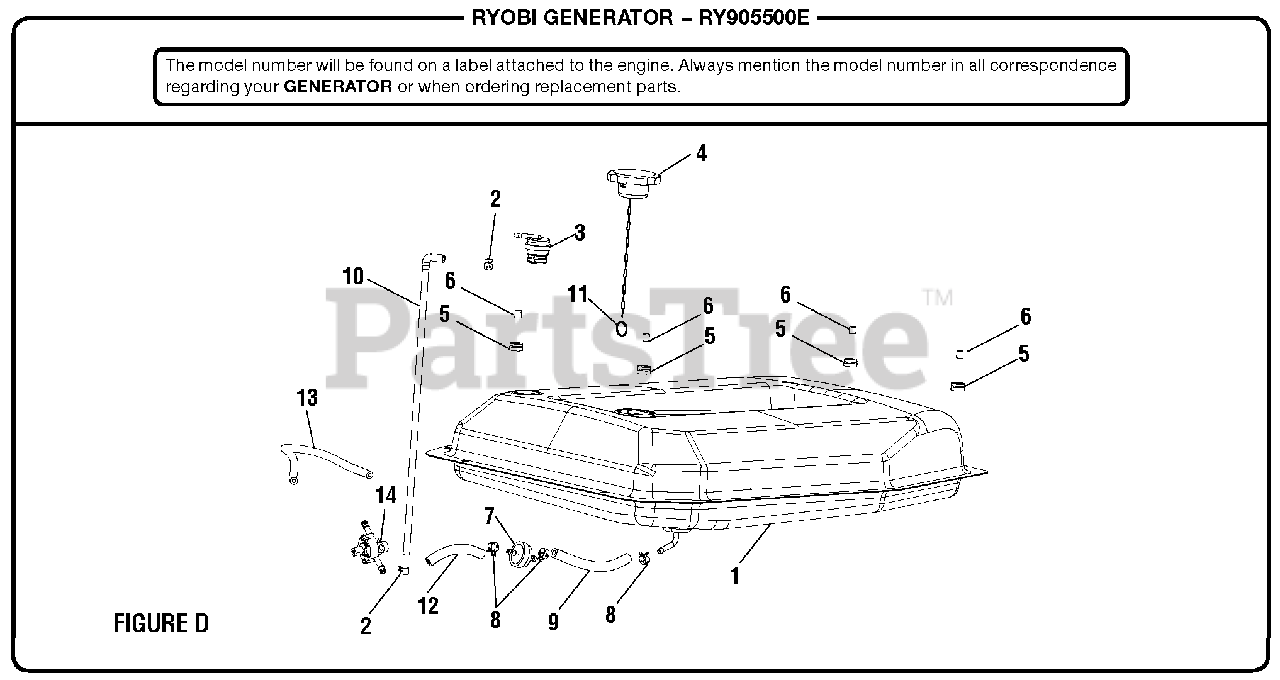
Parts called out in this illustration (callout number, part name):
1	Fuel Tank
2	Fuel Line Clamp (7/16 in.)
3	Vapor Vent
7	Fuel Filter Inline (1/4 in.)
8	Fuel Line Clamp (1/2 in.)
9	Fuel Hose (175 mm)
10	Vapor Hose
11	Ring Clip
12	Fuel Hose (85 mm)
13	Fuel Hose (280 mm)
14	Fuel Valve
